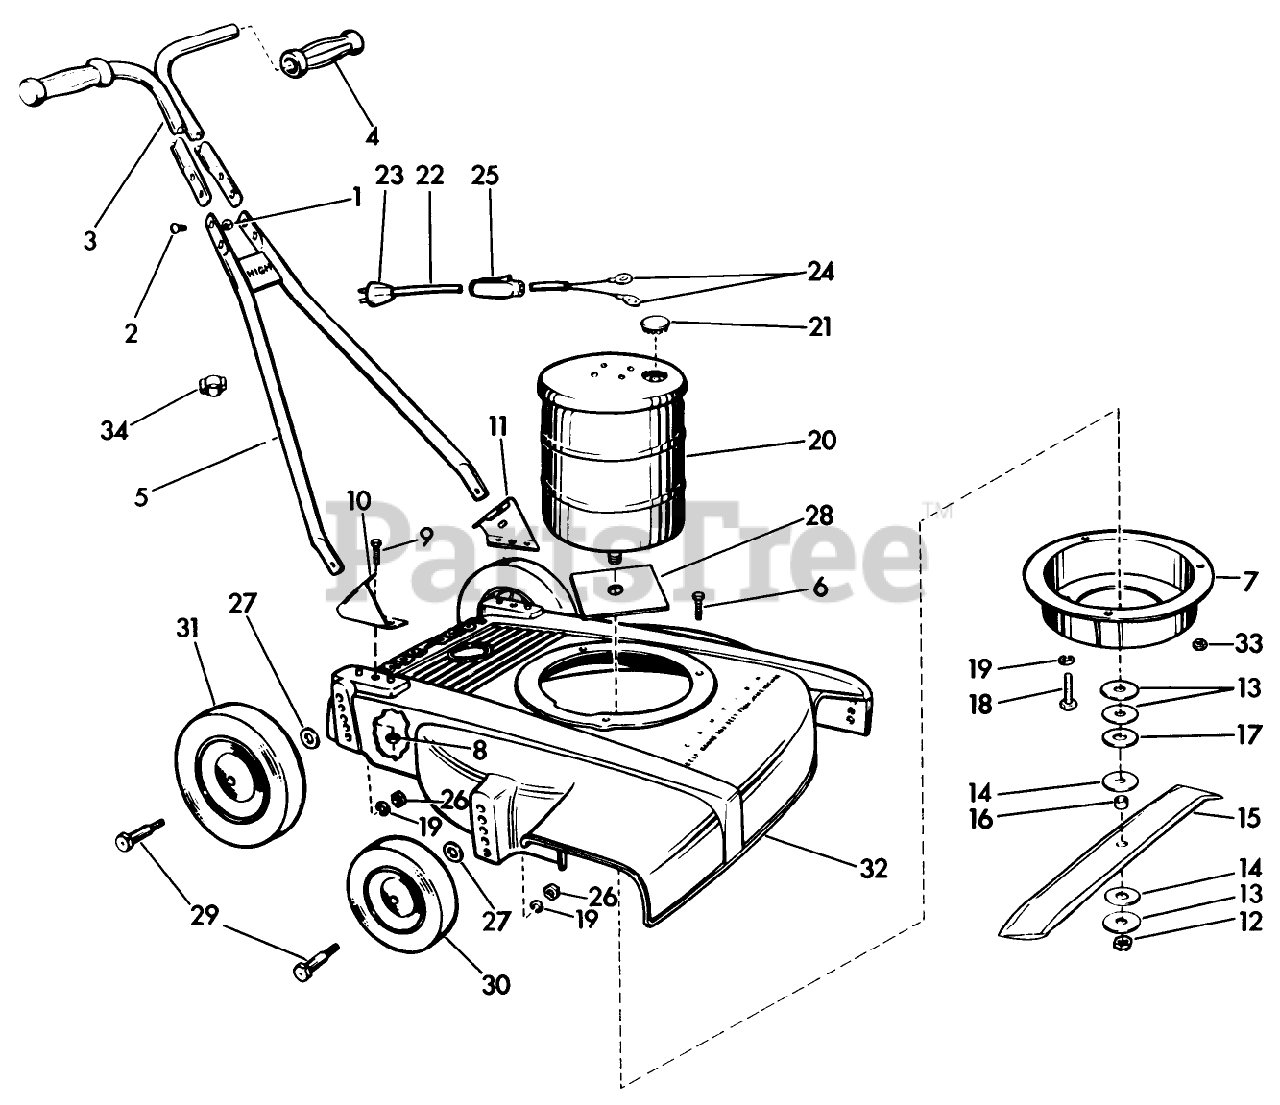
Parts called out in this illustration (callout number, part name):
1	STOP NUT
7	Plate-Adapter
15	Blade-18"
16	Bushing-Blade
17	BLADE WASHER
18	Screw-Motor Mounting
19	WASHER, LOCK
21	Cap-Snap-on
23	Plug-Electric
24	Lug-Electric
25	Switch-Toggle
28	Shield-Dust
32	Housing-18"
34	Clip-Electric Cord
